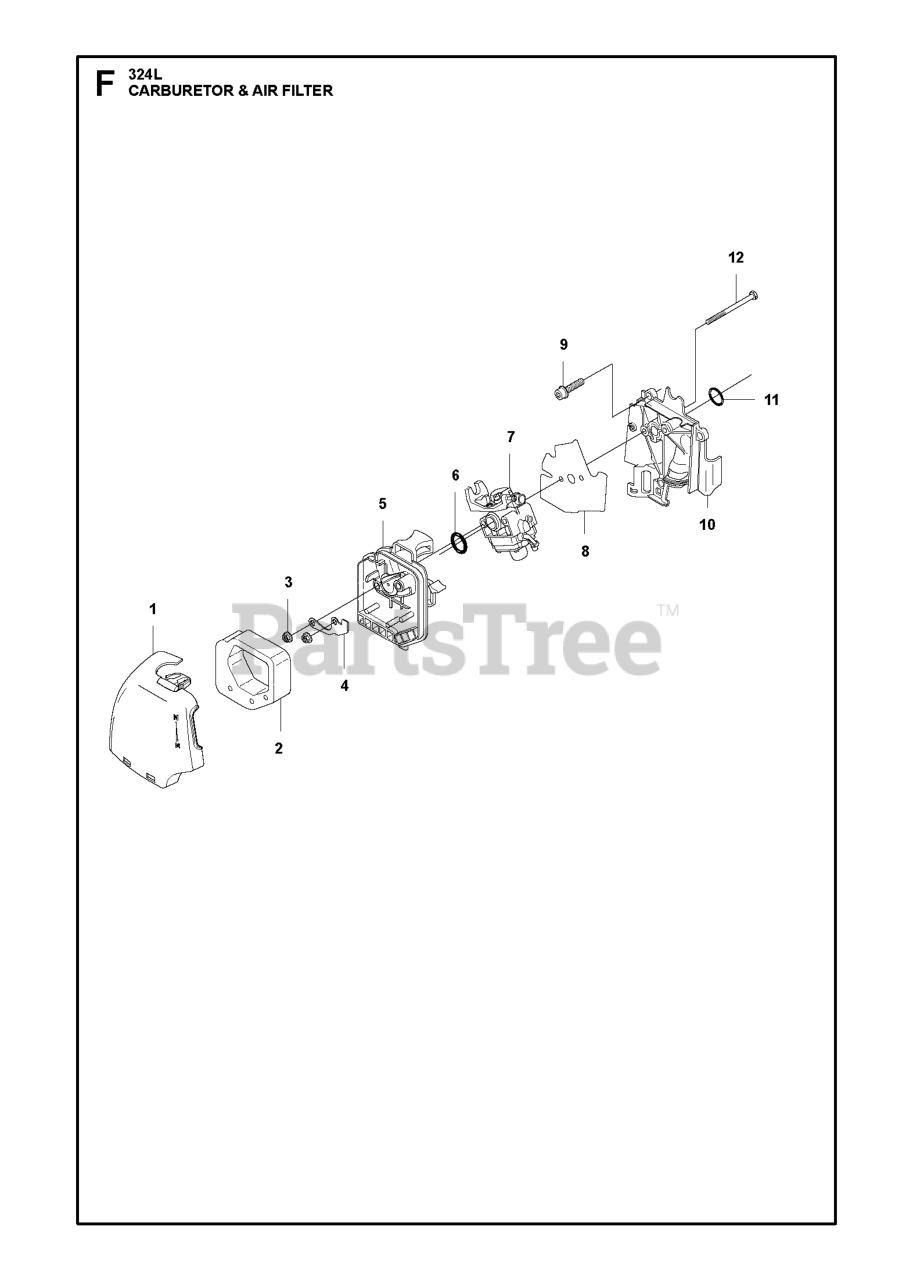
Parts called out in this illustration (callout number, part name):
1	COVER, AIR CLEANER
2	AIR FILTER
7	CARBURETOR
